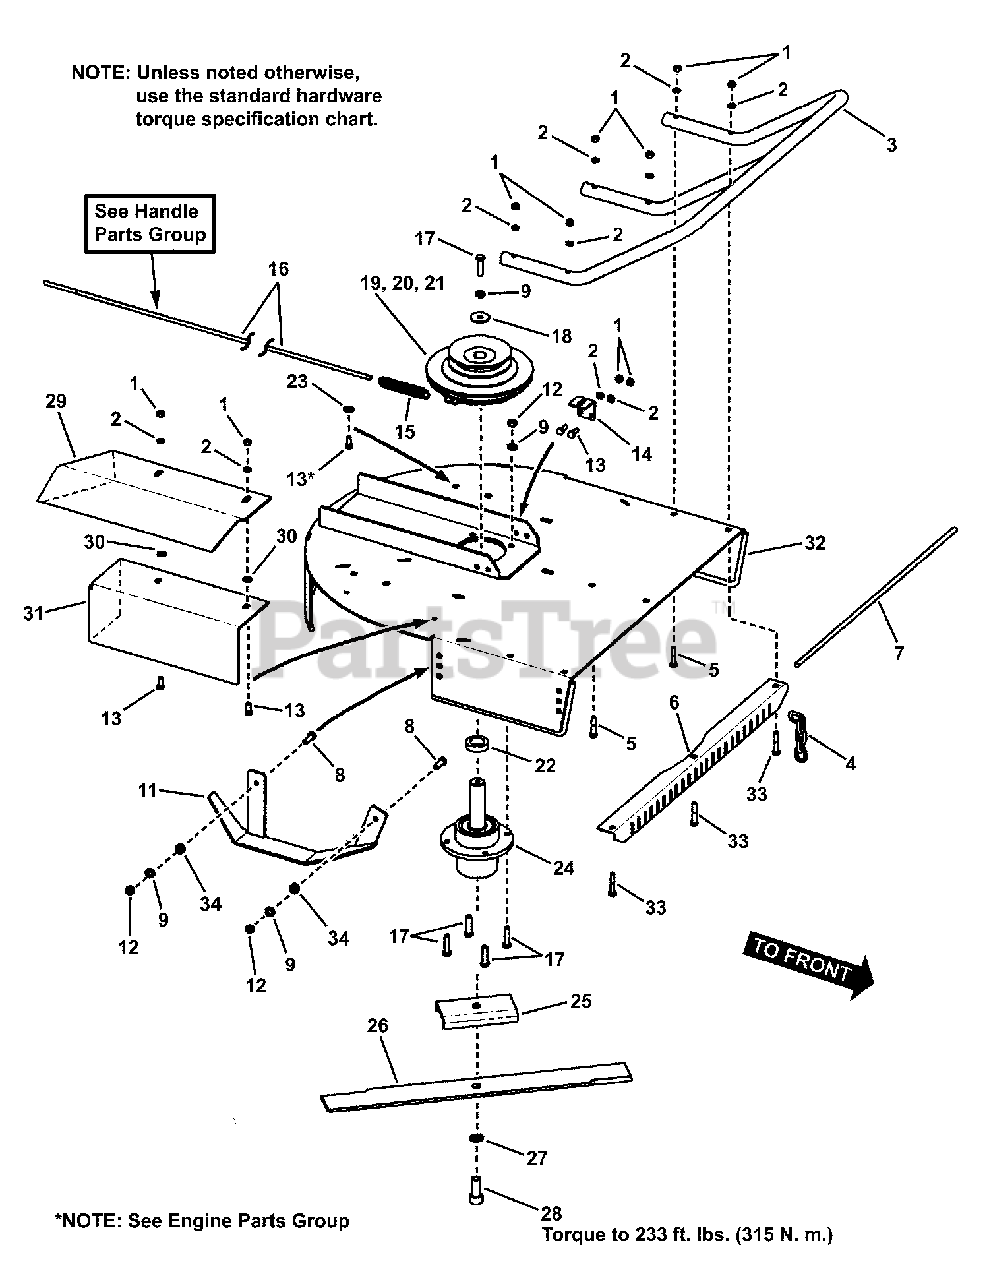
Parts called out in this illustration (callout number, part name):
1	NUT, 5/16-18 Hex, GR 5 or B
2	WASHER, 5/16" Split Lock
3	WELDMENT, Front Bumper
4	CHAIN CURTAIN
5	SCREW, 5/16-18 x 1-1/2" Hex Head Cap, GR 5
6	BRACKET, Chain Curtain
7	ROD, Chain Curtain Mounting
8	SCREW, 3/8-16 x 1 Hex Head Cap, GR 5
9	WASHER, .38 x .68 x .09 Split Lock
11	RIGHT SKID, Blade Deck (weldment)
12	NUT, 3/8-16 Hex, GR 5 or B
13	SCREW, 5/16-18 x 3/4" Hex Head Cap, GR 5
14	BRACKET, Anti-Torque
15	SPRING, Clutch
16	ROD, Blade Clutch Engagement (5/16-18 threaded)
17	SCREW, 3/8-16 x 1-1/2" Hex Head Cap, GR 5
18	WASHER, 7/16 I.D. x 1-1/2" Flat (Heavy Duty)
19	ASSEMBLY, Clutch Brake
20	SCREW, 5/16-18 x 1" Hex Head Cap
21	NUT, 5/16-18 Hex Center Lock
22	SPACER, Clutch
23	WASHER, 3/8" SAE Flat
24	ASSEMBLY, Blade Spindle
25	CHANNEL, Cutting Blade Reinforcement
26	CUTTING BLADE
27	WASHER, 5/8" Split Lock
28	CAPSCREW, 5/8-11 x 1-1/2" Socket
29	DELFECTOR, Discharge (weldment)
30	WASHER, 5/16" SAE Flat
31	COVER, Discharge (weldment)
32	BLADE DECK
33	SCREW, 5/16-18 x 1-3/4 Hex Head Cap, GR 5
34	SPACER, .340 I.D. x .630 O.D. x .310 thick
